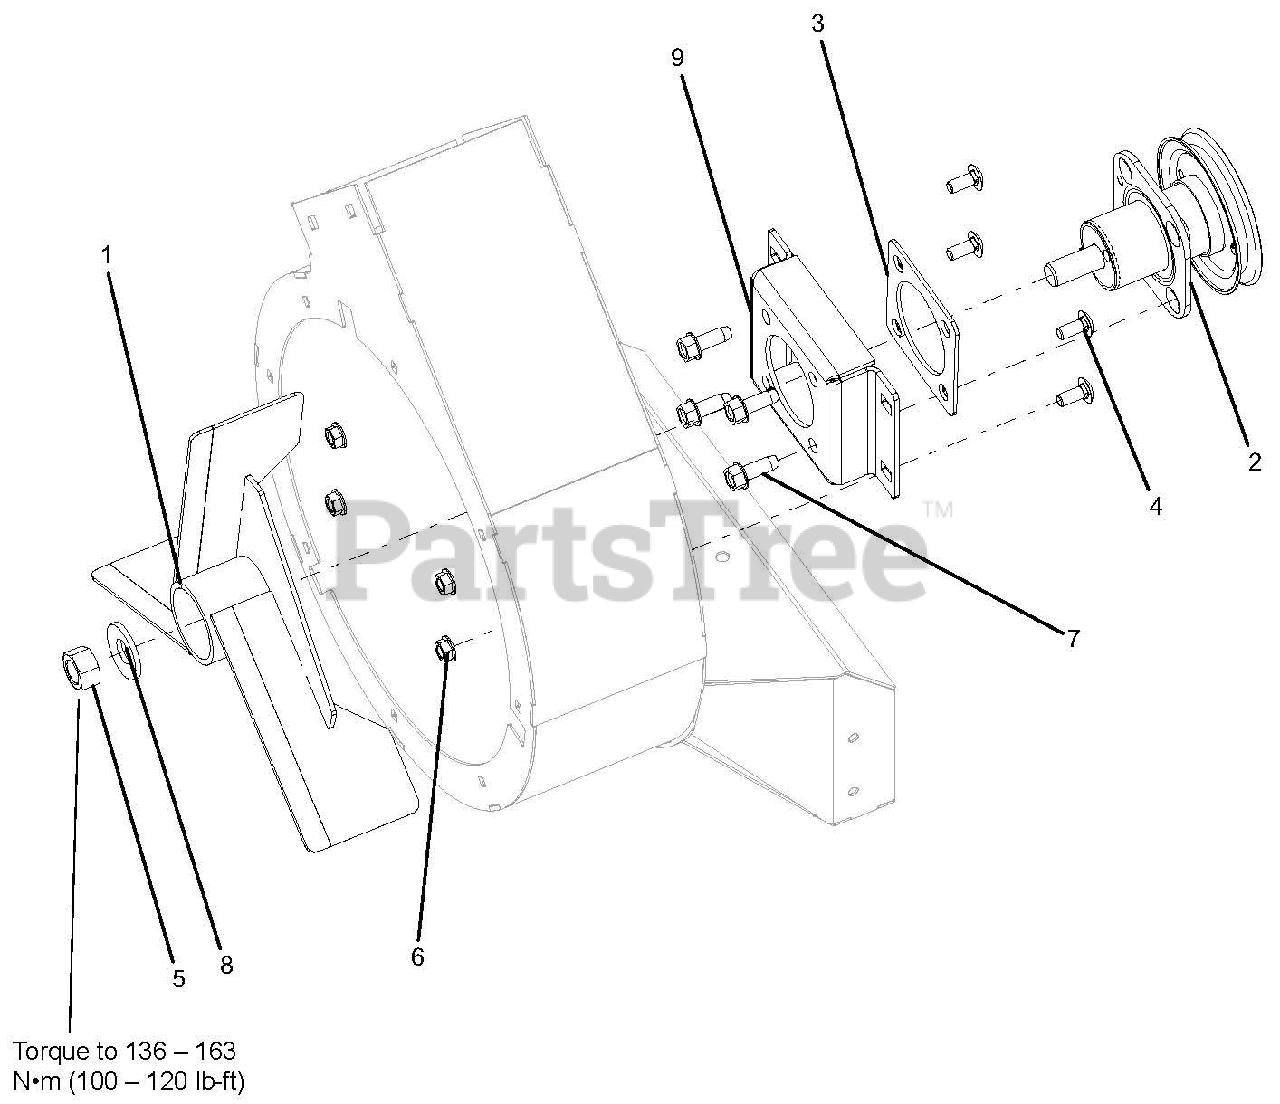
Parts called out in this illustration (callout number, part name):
1	WLDMT, FAN (BLOWER)
2	KIT, DECK SPINDLE ASM (42)
3	SPACER, BAGGER SPINDLE
4	BLT-RHDSSQNK .31-18X.75 G5YZ
5	NUT-HEX .62-18 YWZC
6	NUT-LK-TOP-FLG .31-18 YWZC
7	SCR-TAP .38-16X1.00 HWH TR YZ
8	WSHR-BLVL .669X1.535X.138
9	MOUNT, SPINDLE STANDOFF
